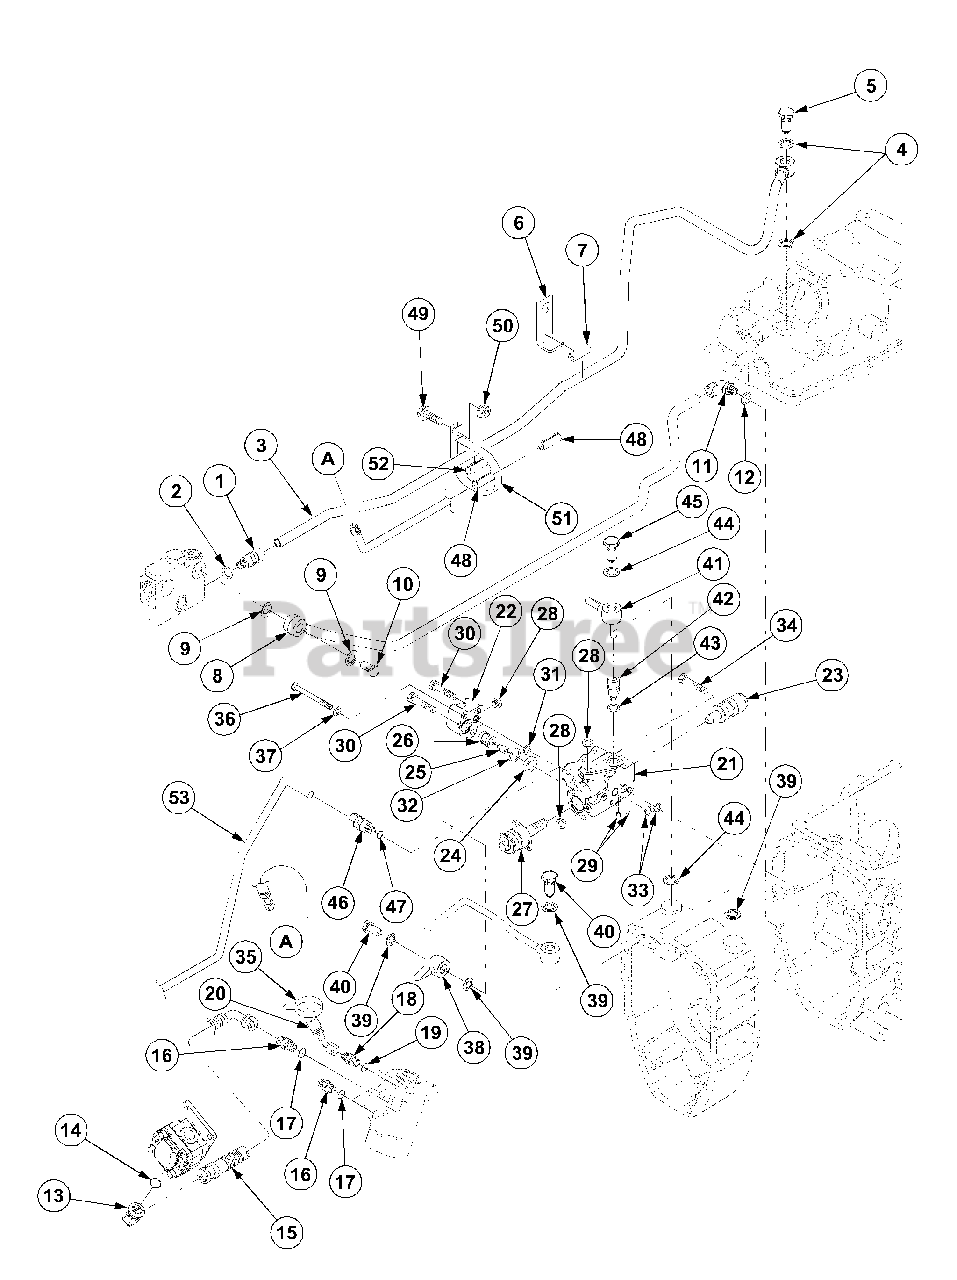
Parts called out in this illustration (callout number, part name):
1	Nipple
3	Pipe A,Pressure
4	Washer,Seal
8	Pipe B,Return
9	Washer,Seal
11	Elbow
13	Elbow 90
16	Adapter
18	Adapter
23	Relief Valve Ass'y.
30	Bolt,w/Washer
34	Bolt,w/Washer
38	Pipe Ind, Pressure
42	Nipple
46	Nipple
49	Bolt,w/Washer
53	Pipe C,Return
